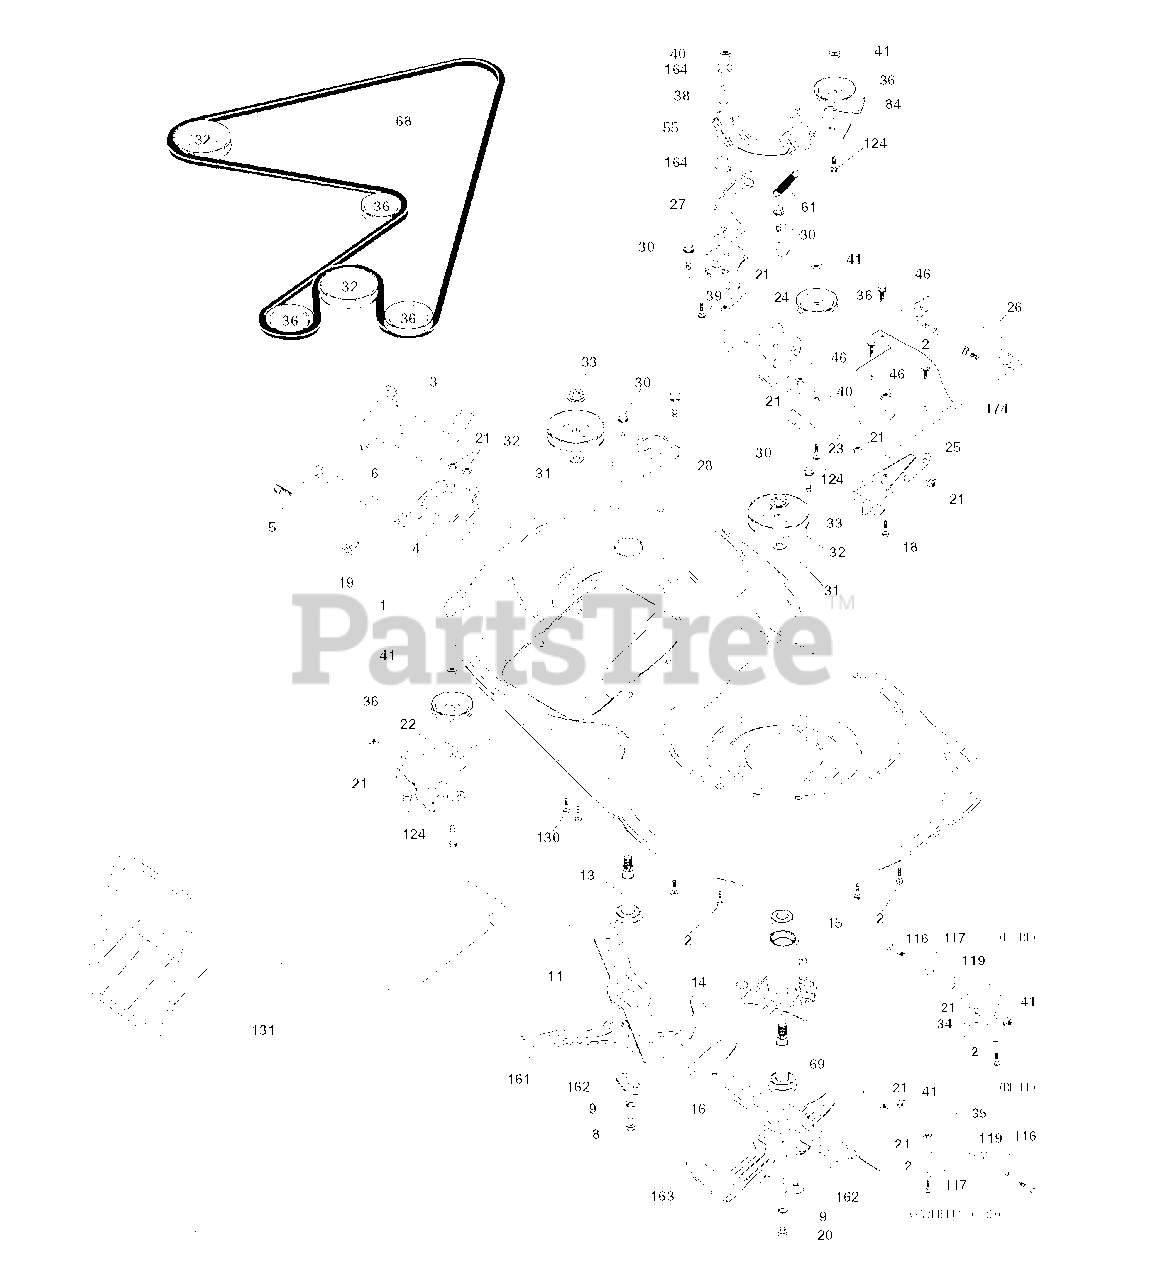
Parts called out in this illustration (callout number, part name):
2	BOLT
3	BRACKET
5	RETAINER-SPRNG RB
6	BAR SWAY
9	LOCKWASHER
11	BLADE.3N1.LH.CRD
13	SHAFT ASM VENT
14	HSG MANDREL
16	BLADE.3N1.RH.CRD
18	BOLT
19	BOLT SHD 5/16-18
21	LOCKNUT
22	BRACKET
23	BRACKET
27	BRACKET
30	SCREW, WASHER HEAD
31	WASHER.SPACER.MANDREL
33	NUT.FLANGE.LOCK.TOP
36	PULLEY.IDLER.4.25
40	LOCKNUT
41	NUT LOCK FLG 3/8-16 UNC
46	SCREW.1/4-20X5/8
55	ARM IDLER
68	HEX-BELT 107 MOWER
69	SHAFT.ASM.W/LWR.BRG.RH.THREAD
84	KEEPER, BELT IDLER
116	BOLT.SHOULDER.3/8-16X3-5/8
117	WHEEL. GUAGE RALLY
124	BOLT.3/8-16X1.50
131	CHUTE BAGGER
164	BRNG T
306	PALNUT 1/4
